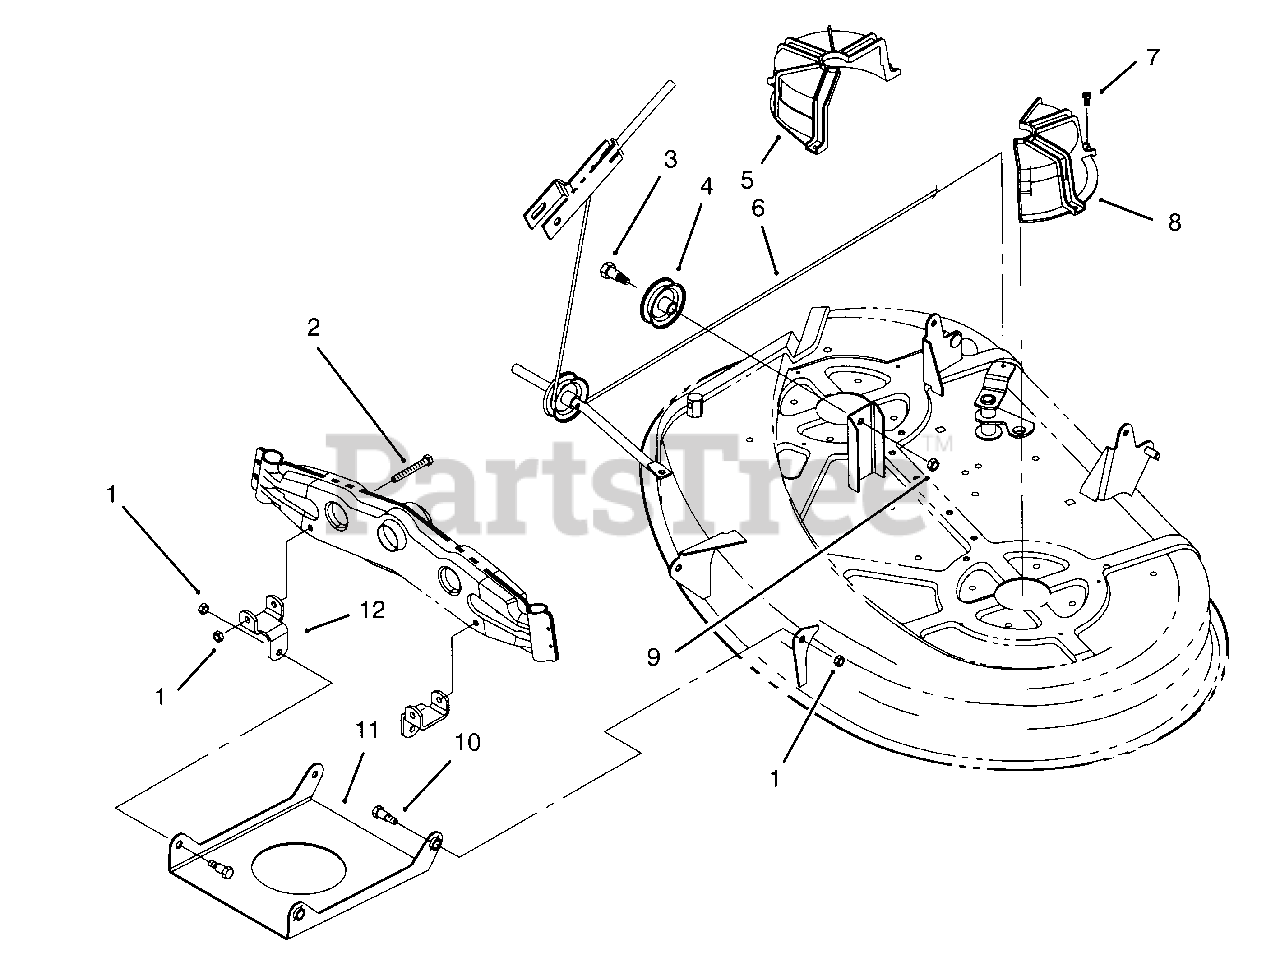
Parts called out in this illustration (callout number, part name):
1	Nut-Lock
2	Screw-Hex Hd. Cap
3	Bolt-Shoulder
4	Pulley-Cable
5	Guide-Deck Belt R.H.
6	Cable-Deck Engage
7	Screw-Thread Cutting
8	Guide-Deck Belt L.H.
9	Nut-Lock
10	Bolt-Shoulder
11	Pan-Front Deck Suspension
12	Bracket-Deck Suspension
